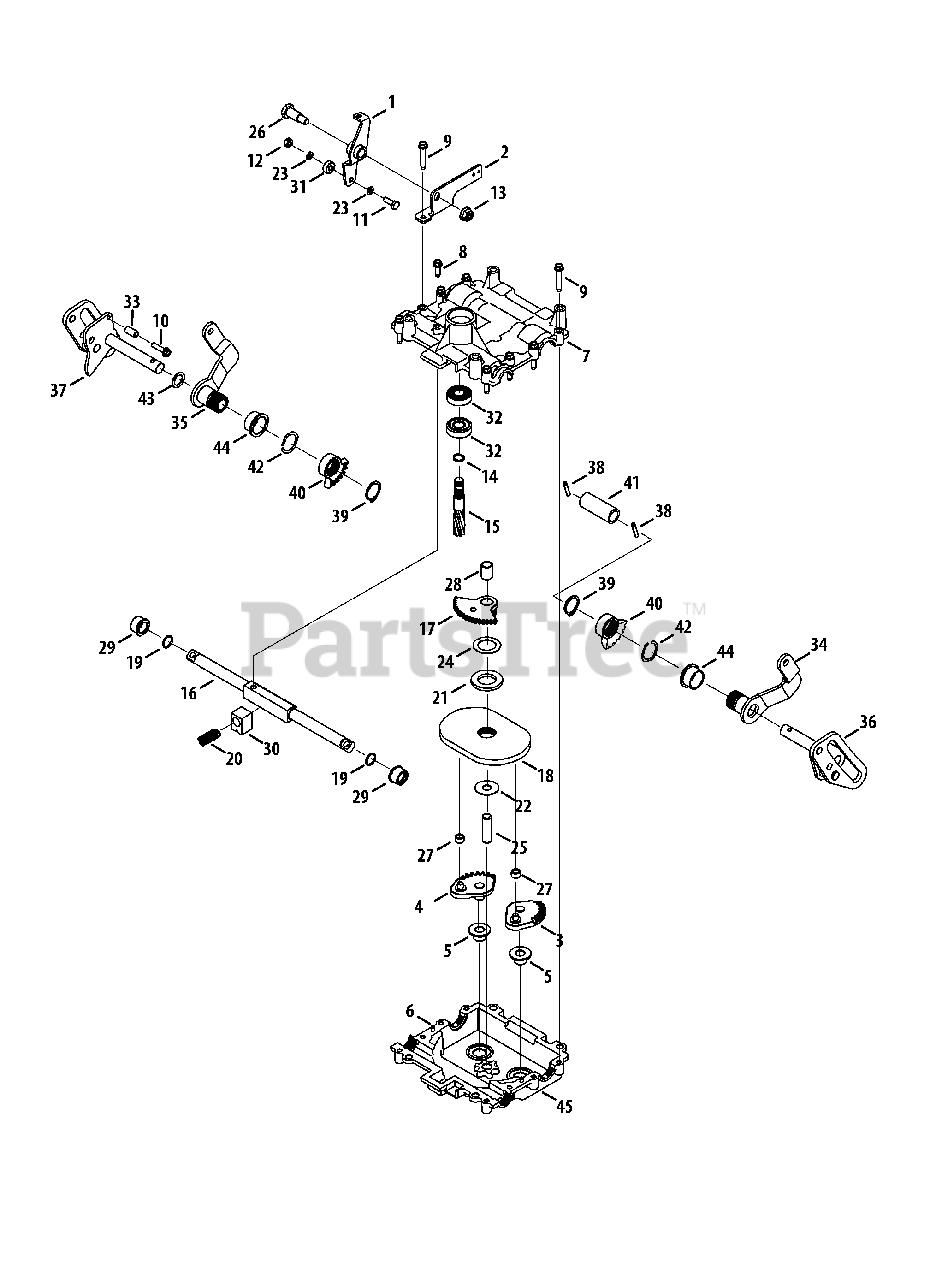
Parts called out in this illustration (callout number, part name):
1	Cam Plate Assembly
2	Neutral Bracket
3	LH Steering Gear Assembly
4	RH Steering Gear Assembly
5	Flange Bearing, .5 x .700
6	Dowel Pin, 3/16 x 1/2
7	Upper Steering Housing
8	Hex Washer Screw, 1/4-20 x 0.750
9	Hex Washer Screw, 1/4-20 x 1.500
10	Hex Washer Screw. 1/4-20 x 1.000
11	Hex Screw, 1/4-20 x .75
12	Flange Lock Nut, 1/4-20
13	Flange Lock Nut, 3/8-16
14	Retaining Ring, .56
15	Pinion Gear, 7-Tooth
16	Synchro Rack Gear
17	Steering Gear, 53-Tooth
18	Hydro Steering Cam
19	O-Ring, .625 x .07
20	Compression Spring, .531 x 1.25
21	Flat Washer, 1.01 x 1.75 x .172
22	Flat Washer, .508 x 1.325 x .040
23	Flat Washer, .260 x .455 x .048
24	Thrust Washer, 1.007 x 1.542 x .03
25	Steering Shaft
26	Shoulder Screw, 3/8-16 x .500 x .835
27	Sleeve Bearing, .437 x .3425
28	Sleeve Bearing, .623 x .5025 x .800
29	Flange Bearing, .625 x .875
30	Rack Caster Bearing
31	Ball Bearing, .25 x .6875 x .25
32	Ball Bearing, .5625 x 1.375 x .4375
33	Spacer, .260 x .375 x .75
34	Arm Asm, Lh, Hydro, Vert
35	Arm Asm, Rh, Hydro, Vert
36	Cam Asm, Lh, Painted
37	Cam Asm, Rh, Painted
38	Pin, Spirol, 3/16 X 1.00, Hd
39	Ring, Snap, 1.0 Dia Shaft
40	Gear, Steering, 26t
41	Tube, Cam, Speed
42	Spr, Wave, M, 24.22x32x1.98, Gap
43	Wash, Flat, .635x.930x.033, Ht
44	Brg, Sleeve, 1.2 Od X 1.00 Id
45	Lower Steering Housing
